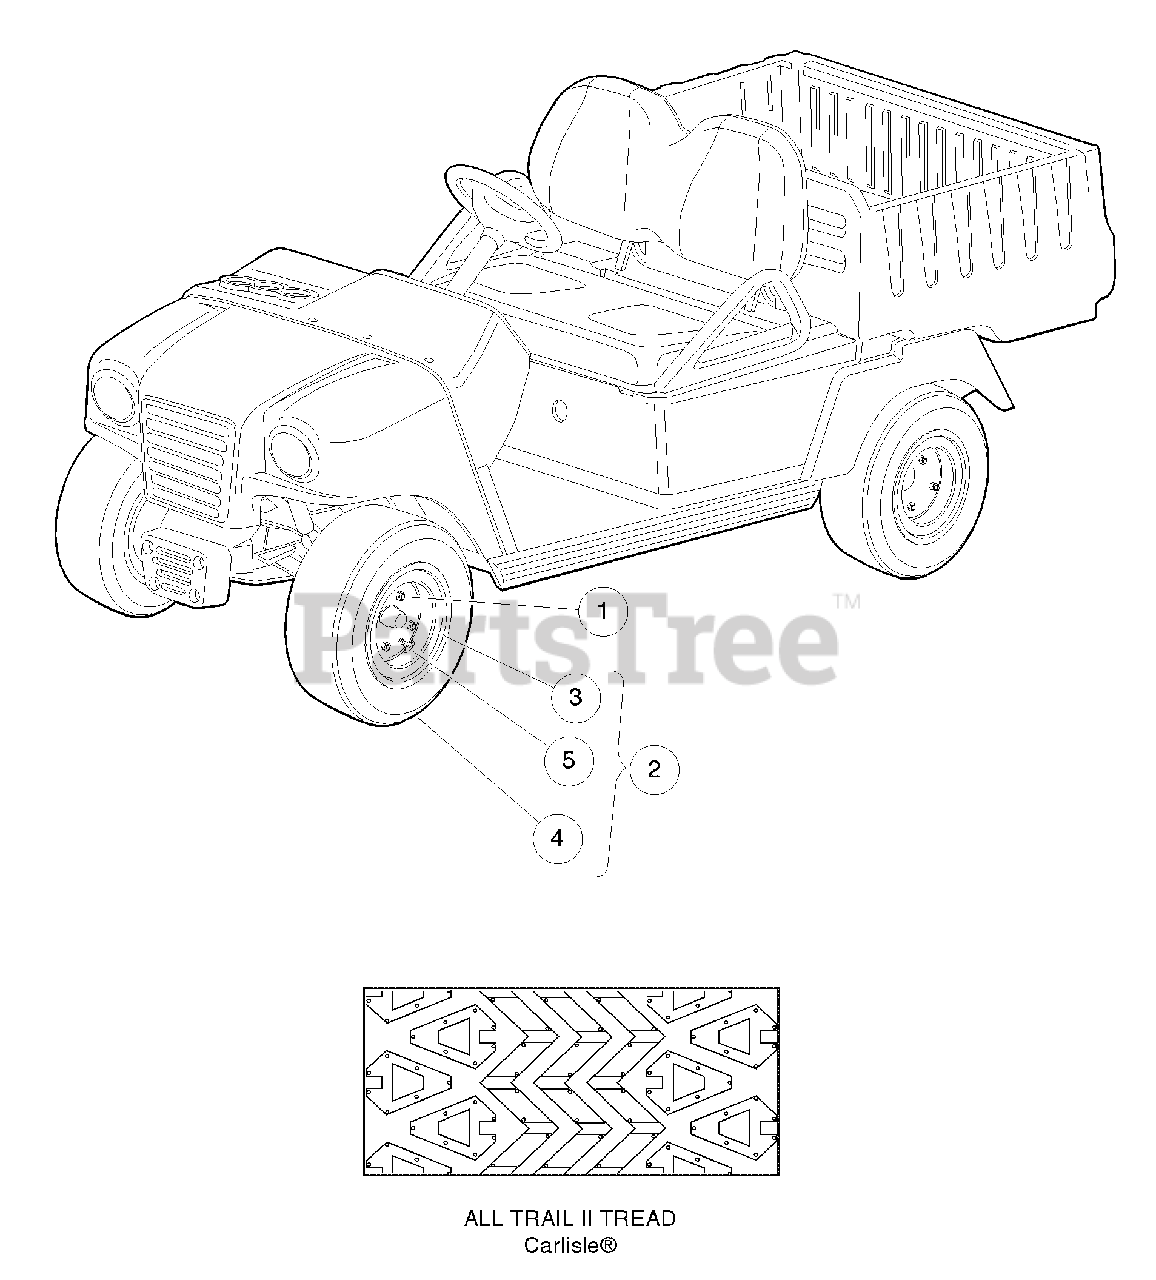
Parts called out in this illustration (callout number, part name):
1	.500-20 Unf Lug Nut
2	Tire Assembly, All Trail II
3	Wheel Rim, Gray
4	Tire, Unmounted, All Trail II
5	Valve Stem
